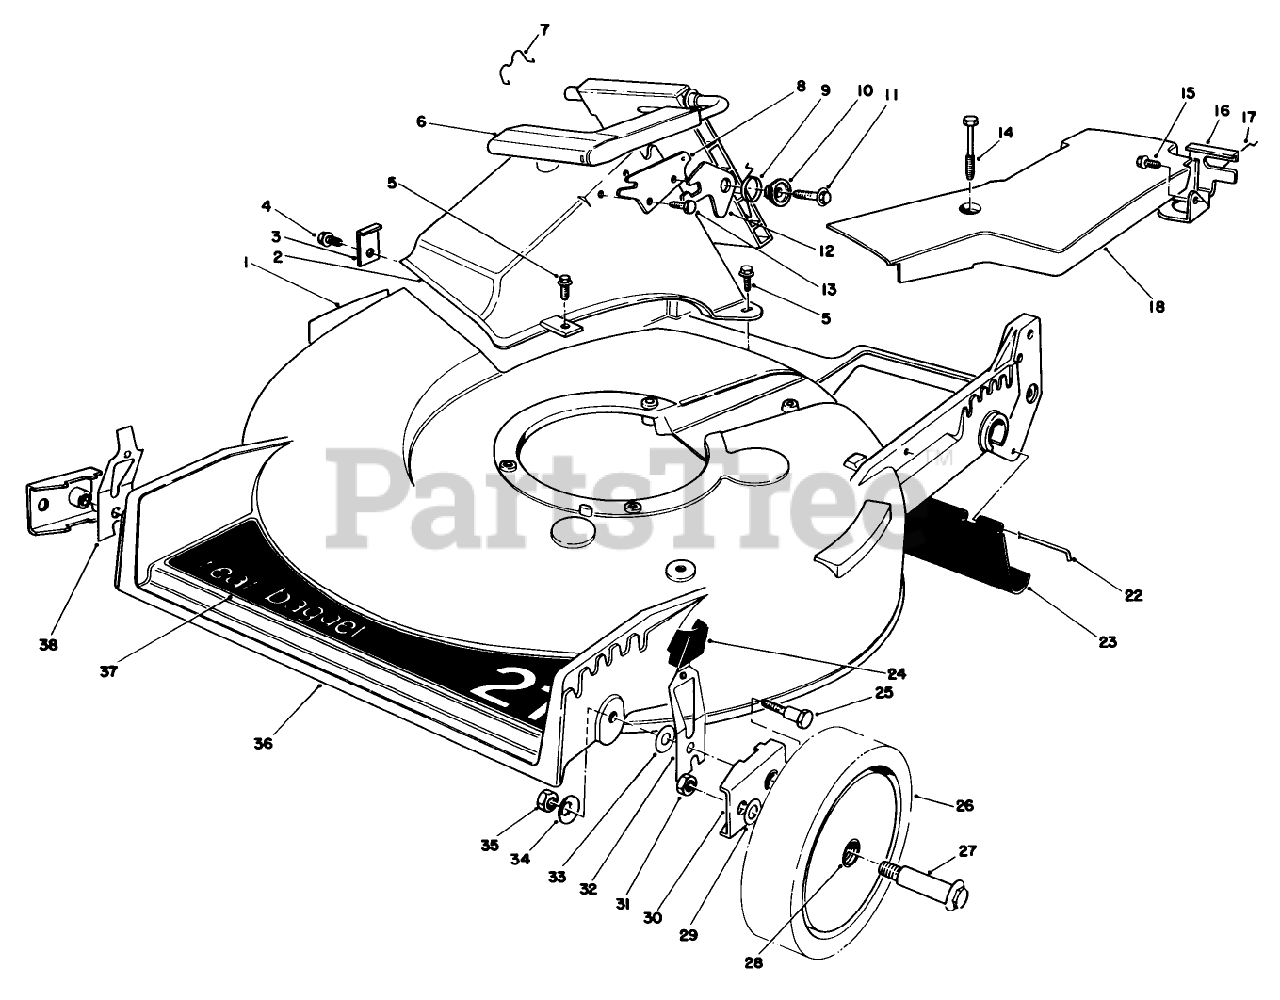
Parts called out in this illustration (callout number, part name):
1	DECAL-DANGER
3	TUNNEL CLIP
4	SCREW
5	SCREW-HWH
7	DOOR RET SPRING
8	DOOR LATCH PLATE
9	TORSION SPRING
10	DOOR SPACER
11	SCREW-HWH
12	SAFETY LATCH
13	SCREW-PLASTITE
14	SCREW-HWH
15	SCREW-THD ROLL, HWH
17	RETAINER-CABLE
22	ROD-SHIELD
24	KNOB-ARM
25	PIVOT SCREW
27	BOLT-WHEEL
28	BUSHING
29	WASHER
30	HP PIVOT ARM ASM
33	WASHER-PIVOT
34	WASHER-BELLEVILLE
35	NUT-LOCK, NI
36	21 SP RB HSG/DECAL
